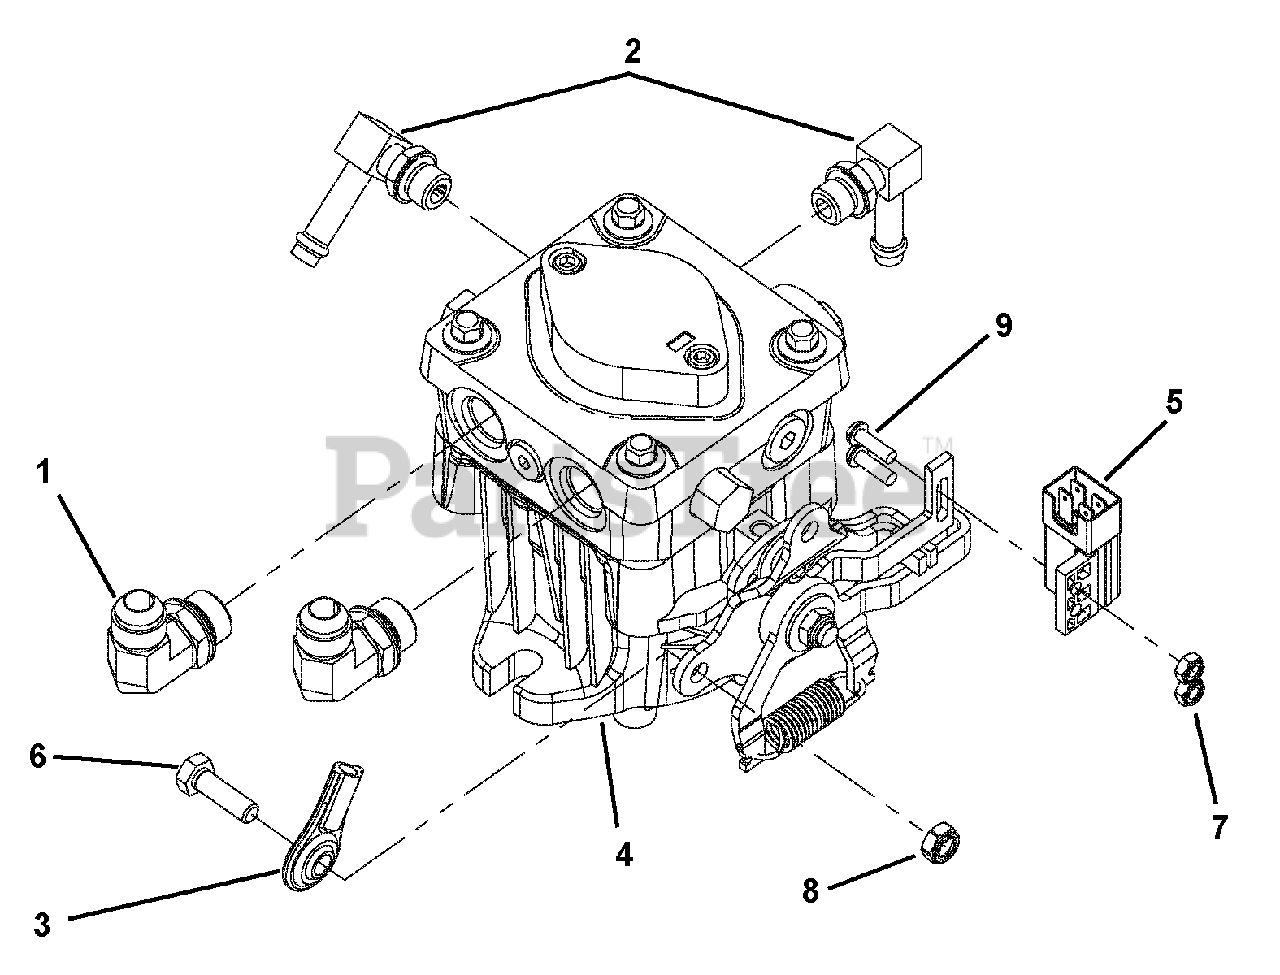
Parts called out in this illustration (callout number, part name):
1	Fitting, Includes O-Ring
2	Fitting -Adaptor .562-18 Steel Thread
3	Rod End, 5/16 RH -Female
4	Pump, Left Hand
5	Switch, Plunger Diametral Pitch -N.O. -N.C.
6	Bolt, Hex .31 x 1.00 Grade 5
7	Nut, Locking, Nylon 10-24 w/Insert
8	Nut, Locking, Nylon .312-18
9	Screw, Machine 10-24 x .62 P/HD
